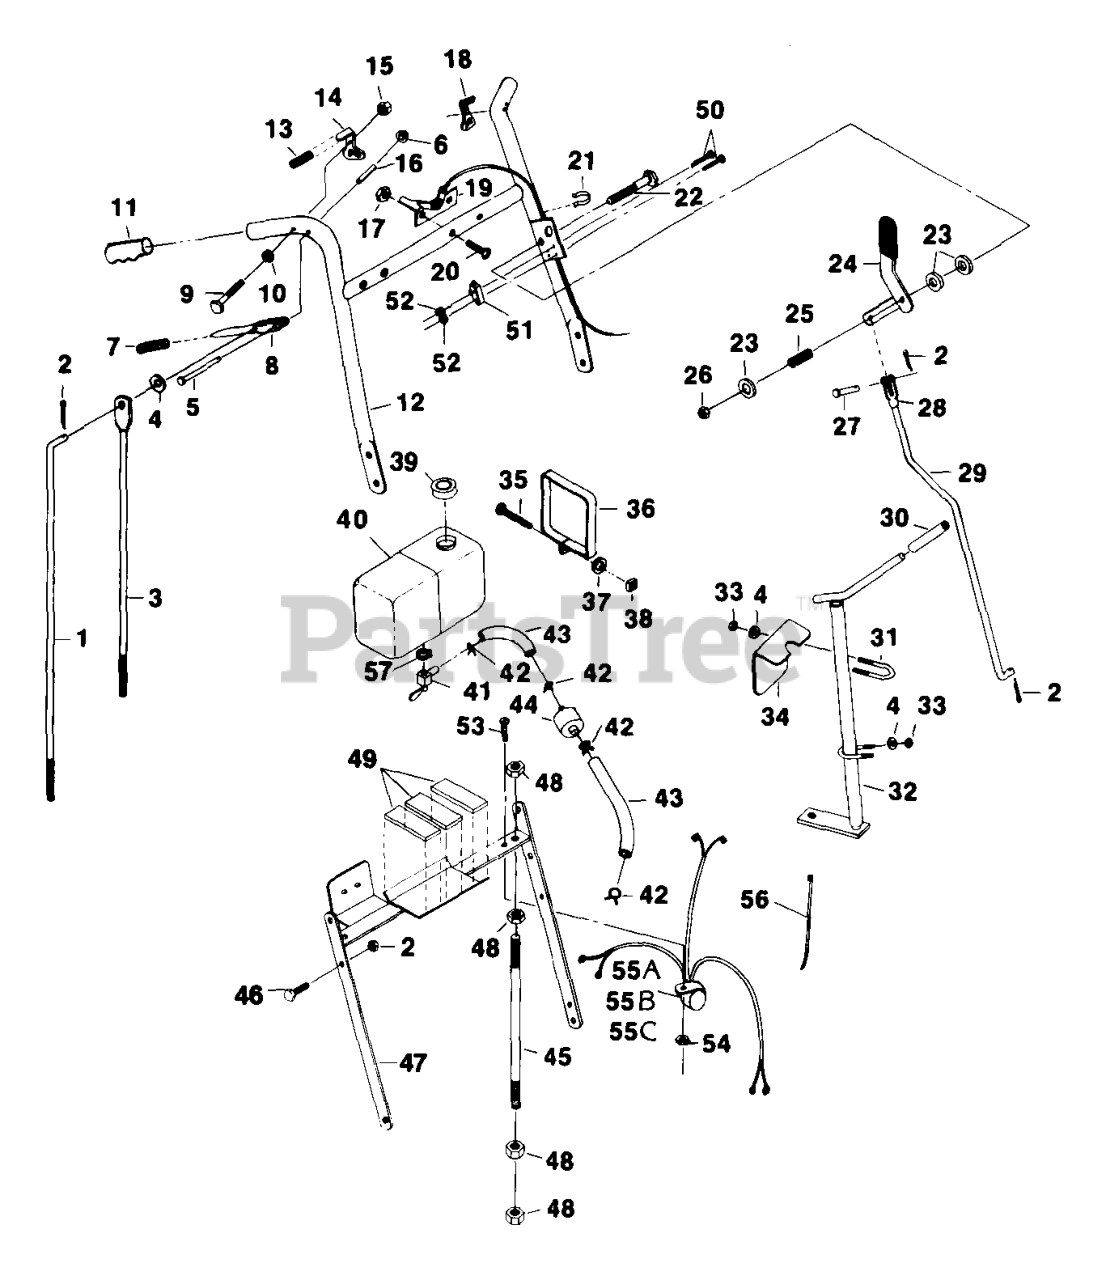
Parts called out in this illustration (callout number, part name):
1	LINKAGE,BRAKE
2	PIN-COTTER
3	LINKAGE,CALIPER
6	NUT-PUSH
7	GRIP-LEVER, DRIVE
8	DRIVE LEVER ASM
10	WASHER-SPRING
13	GRIP-LATCH
14	LATCH,W/GRIP RH
15	NUTTORQUE ZNKPLT
16	PIN-ROLL
18	LATCH,W/GRIP LH
21	CLIP-CABLE
25	SPRING-COMPRESSION
27	PIN-CLEVIS
28	YOKE-ADJUSTABLE
29	LINKAGE,BLADE DRIVE
38	NUT-SQH
49	PAD,PLASTIC TANK
56	TIE-CABLE
57	CLAMP-HOSE
